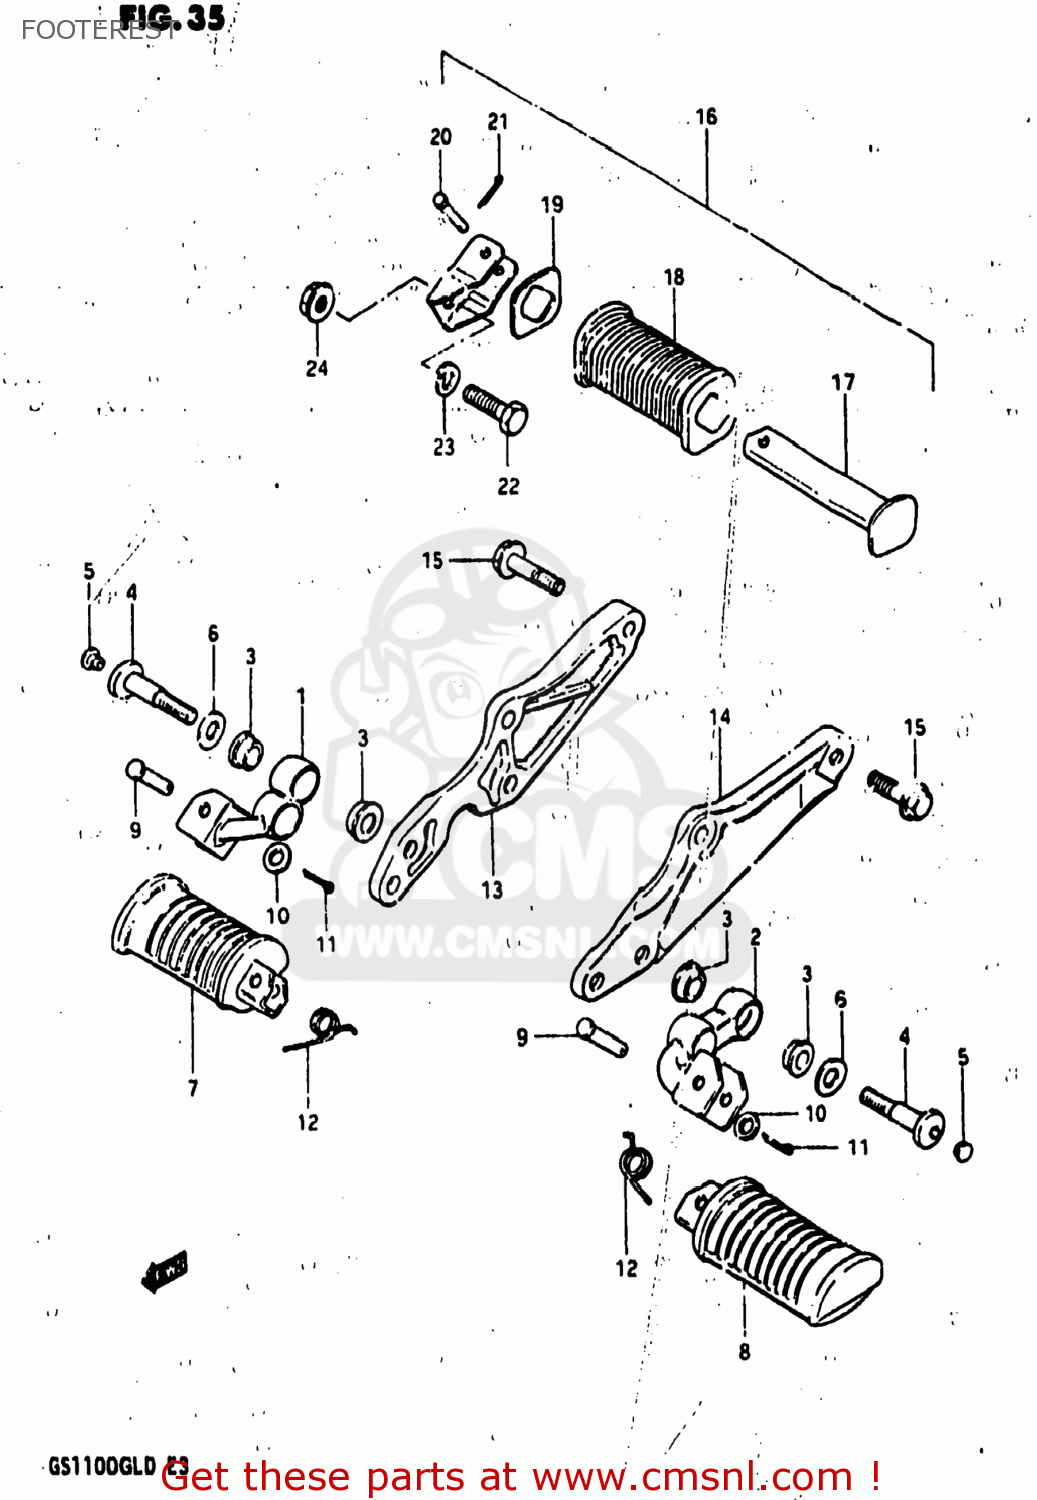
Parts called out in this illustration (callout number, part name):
1	BAR,FRONT FOOTREST
2	BAR,FRONT FOOTREST,LEFT
3	BUSH
4	BOLT
5	CAP
6	WASHER(10.5X28X2.3)
7	RUBBER,FRONT FOOTREST
8	FOOTREST
9	PIN
10	WASHER
11	PIN 20X20
12	SPRING
13	BRACKET
14	BRACKET
15	BOLT
16	FOOTREST ASSEMBLY,REAR
17	BAR,REAR FOOTREST
18	RUBBER,REAR FOOTREST
19	WASHER,REAR FOOTREST RUBBER
20	PIN
21	PIN 20X20
22	BOLT,M10X1.25X
23	LOCK WASHER
24	NUT
